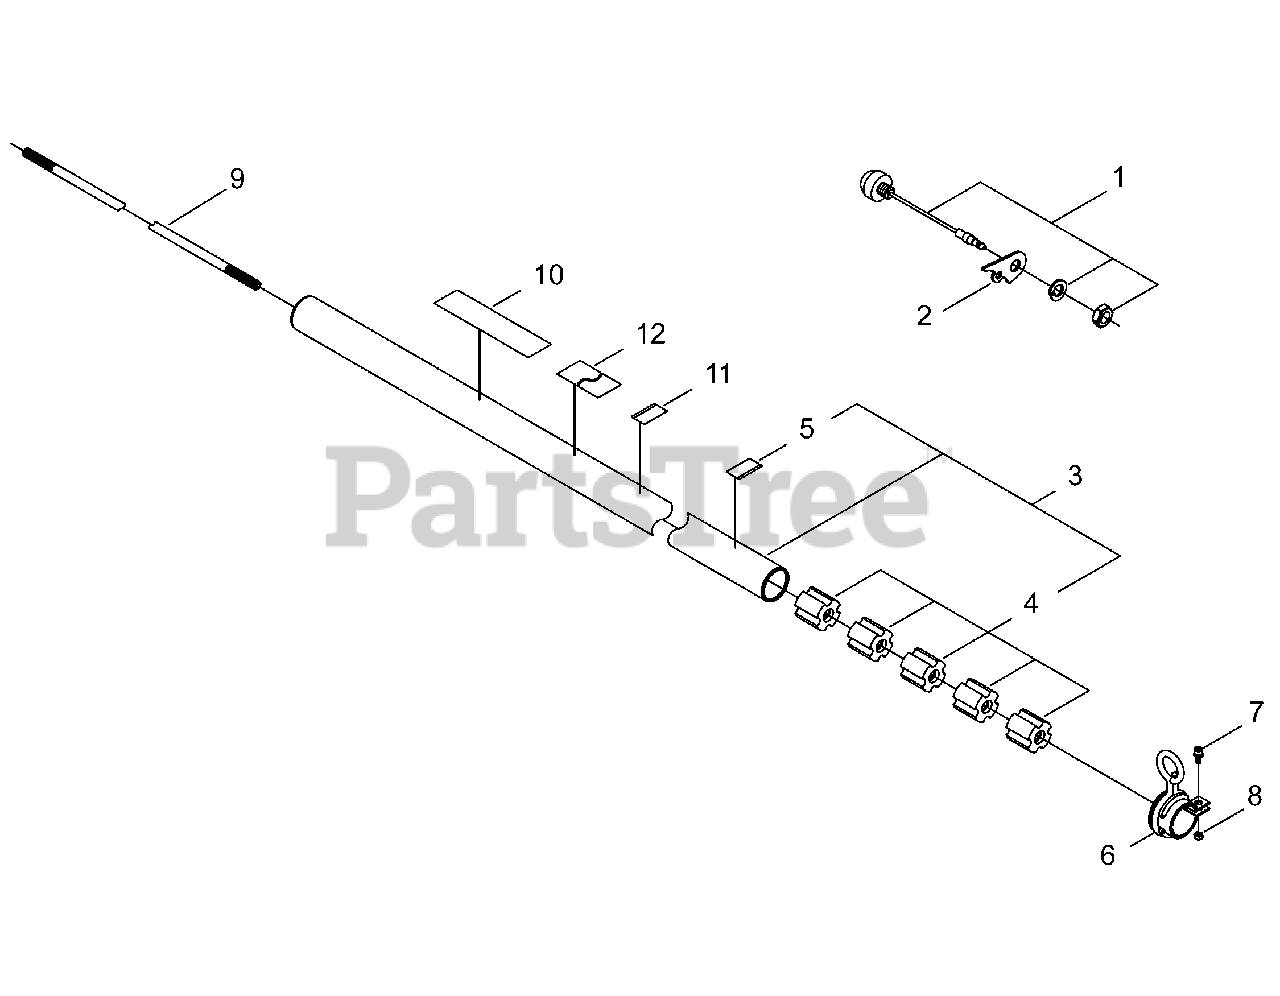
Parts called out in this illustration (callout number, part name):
1	SWITCH, ON-OFF
2	BRACKET
3	MAIN PIPE ASSY
4	BUSHING
5	LABEL - ALIGNMENT
6	HANGER
7	BOLT M5×12
8	NUT M5
9	DRIVESHAFT
10	LABEL, SHINDAIWA PROFESSIONAL
11	LABEL, HANDLE
12	LABEL, CAUTION (BLADE CAPABLE)
